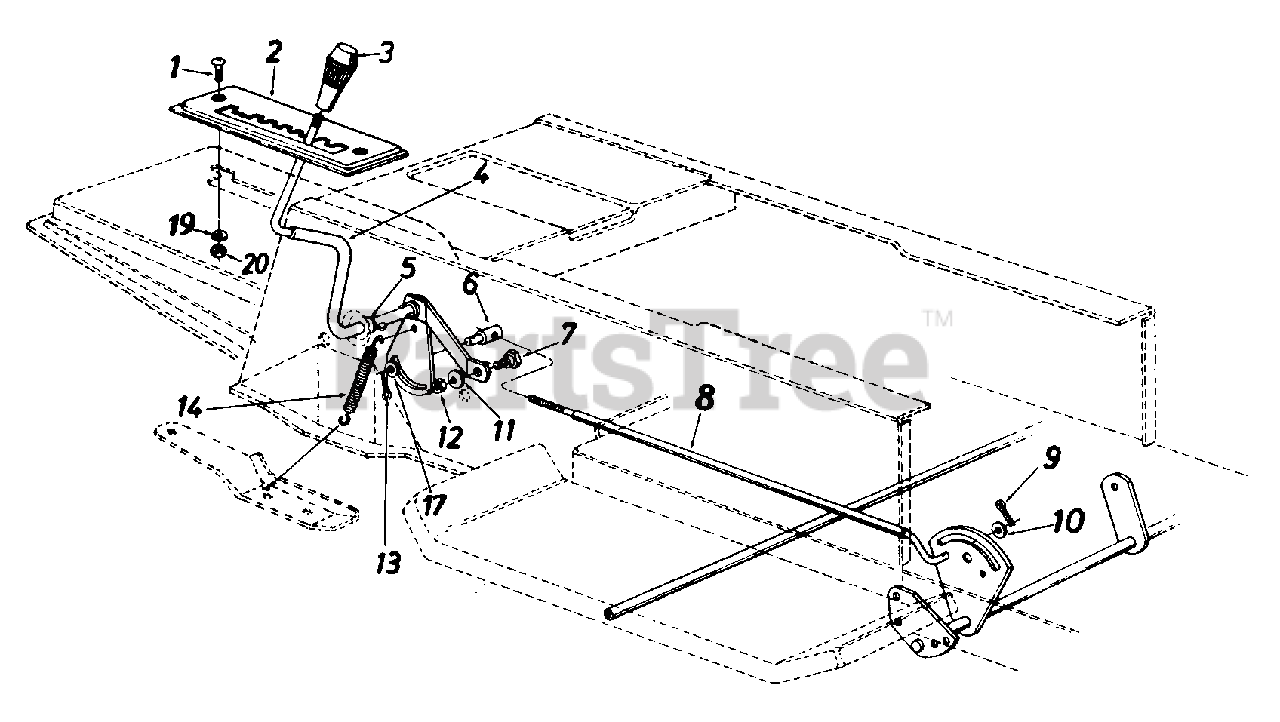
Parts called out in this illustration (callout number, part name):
1	Truss Mach. Scr. 1/4-20 x .75" Lg.
4	Speed Selector Cam Ass'y.
5	Flat Washer .53" I.D. x .93
6	Ferrule 3/8-24 x .37" Dia.
7	Shoulder Bolt
8	Speed Control Link
9	Cotter Pin 3132" Dia. x .75"
10	Fl-Wash. .469" I.D. x .88"
11	L-Wash. 5/16" I.D.
12	Hex Nut 5/16-18 Thd.
13	Cotter Pin 3132" Dia. x .75"
14	Spring .38" O.D. x 3.18" Lg.
17	Fl-Wash. .385" I.D. x .62"
19	L-Wash. 1/4" I.D.
20	Hex Nut 1/4-20 Thd.
